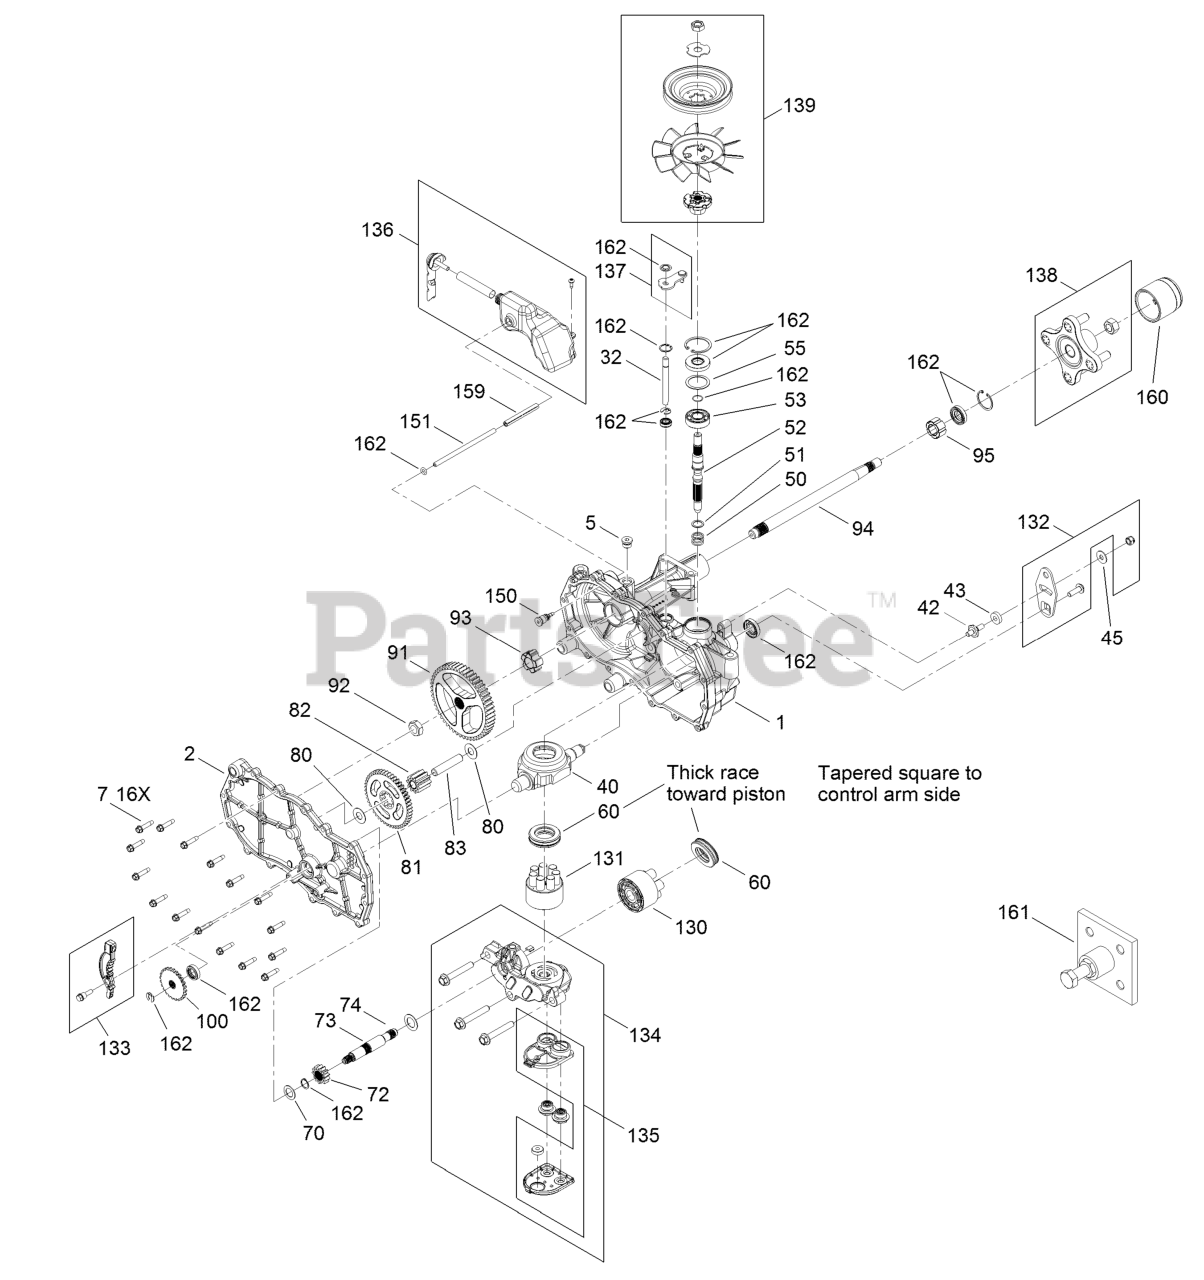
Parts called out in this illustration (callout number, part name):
1	MAIN HOUSING ASM
2	HOUSING SIDE KIT
5	PLUG-THREAD, STRAIGHT
7	SCREW-HHF
32	ROD-BYPASS
40	SWASHPLATE-TRUNNION
43	PUCK-FRICTION
52	SHAFT-INPUT
53	BEARING-BALL
60	BEARING-THRUST
70	WASHER-FLAT
72	GEAR-PINNION, 13T
73	SHAFT-MOTOR
80	Washer
81	GEAR-10T/48T
82	GEAR-JACKSHAFT, 10T
83	PIN-JACKSHAFT
91	GEAR-BULL
93	BUSHING-INBOARD
94	SHAFT-AXLE
95	BEARING-SLEEVE
100	DISC-BRAKE, COG
130	CYLINDER BLOCK KIT
131	PUMP BLOCK ASM
132	CONTROL ARM KIT
133	BRAKE ARM KIT
134	CENTER SECTION FILTER KIT
135	FILTER KIT
136	LH EXPANSION TANK KIT
137	BYPASS ARM KIT
138	HUB KIT
139	FAN PULLEY KIT
150	FITTING-SAE
159	CASE-TUBE
160	CAP-AXLE
162	SEAL AND RING KIT
